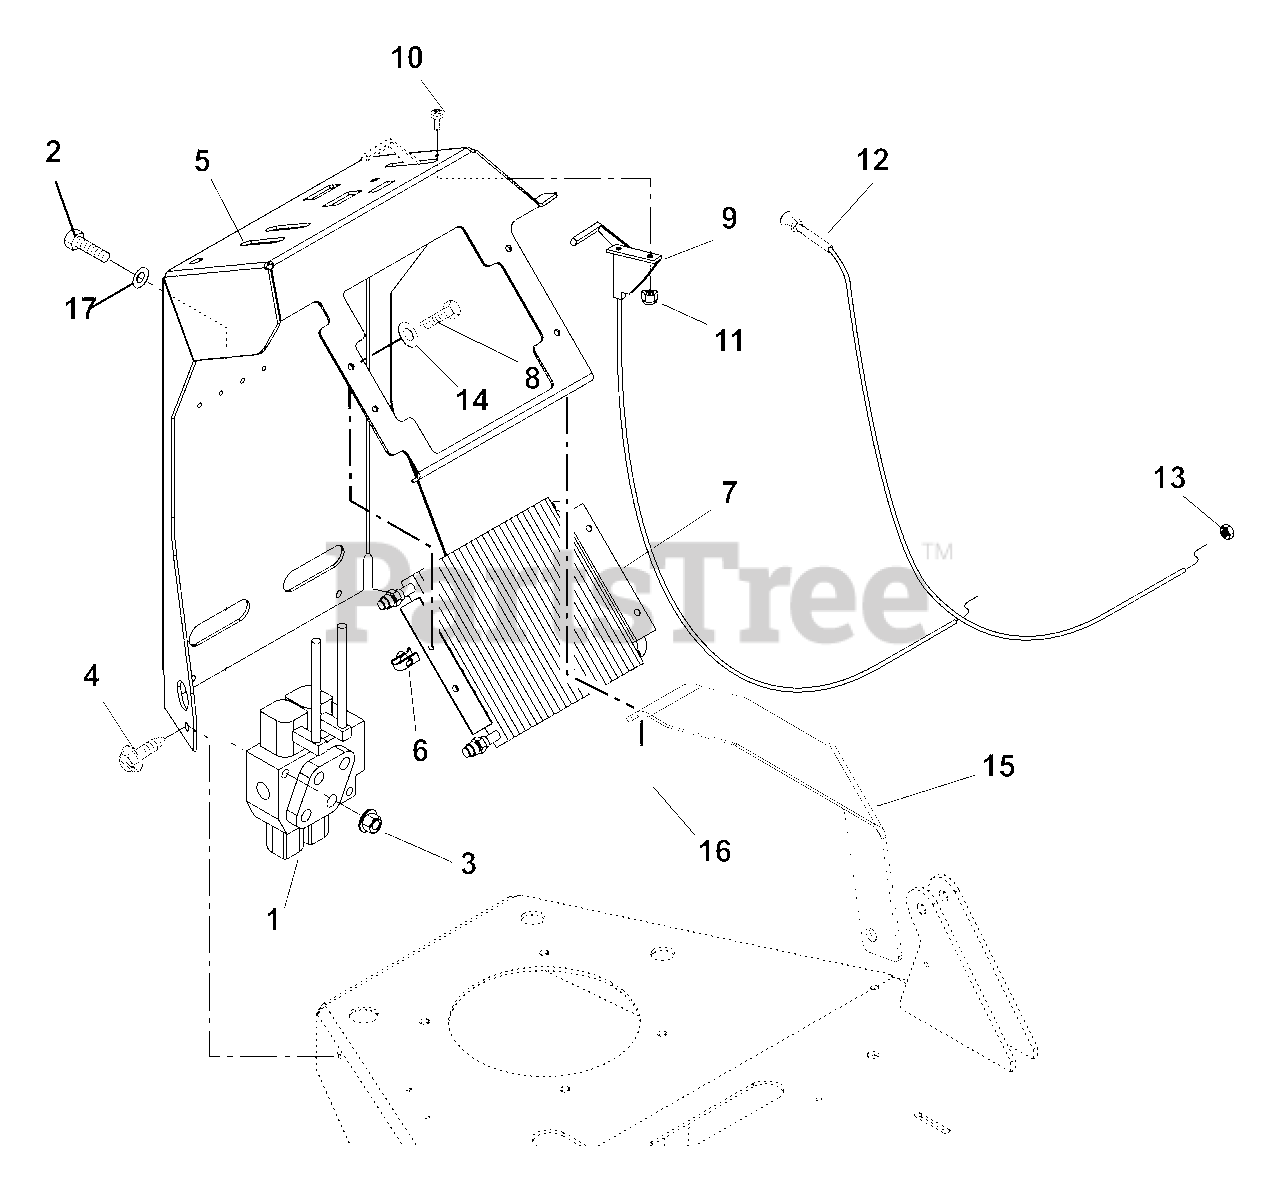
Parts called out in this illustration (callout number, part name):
1	Valve, 2 Spool
2	Bolt-Hex .31-18 x 1.75 Grade 5
3	Nut-Locking-Top-Flange .31-18
4	Screw-Tapping .38-16 x .75 Hex Washer Head
5	Panel, Control
6	Nut-Retainer .25-20 x .56
7	Cooler, Oil
8	Bolt-Hex .25-20 x .75 Grade 5
9	Cable, Control
10	Screw-Machine 10-24 x .50 Hex Washer Head
11	Nut-Locking-Nylon 10-24 with Insert
12	Cable, Choke (021)
12	Cable, Choke (022)
13	Nut-Jam .38-24
14	Washer-Flat-Steel .28 x .62 x .065
15	Brace, Instrument Panel-Left Hand
16	Screw-Tapping .25-20 x .50 Hex Washer Head
17	Washer-Flat-Steel .344 x .688 x .065
